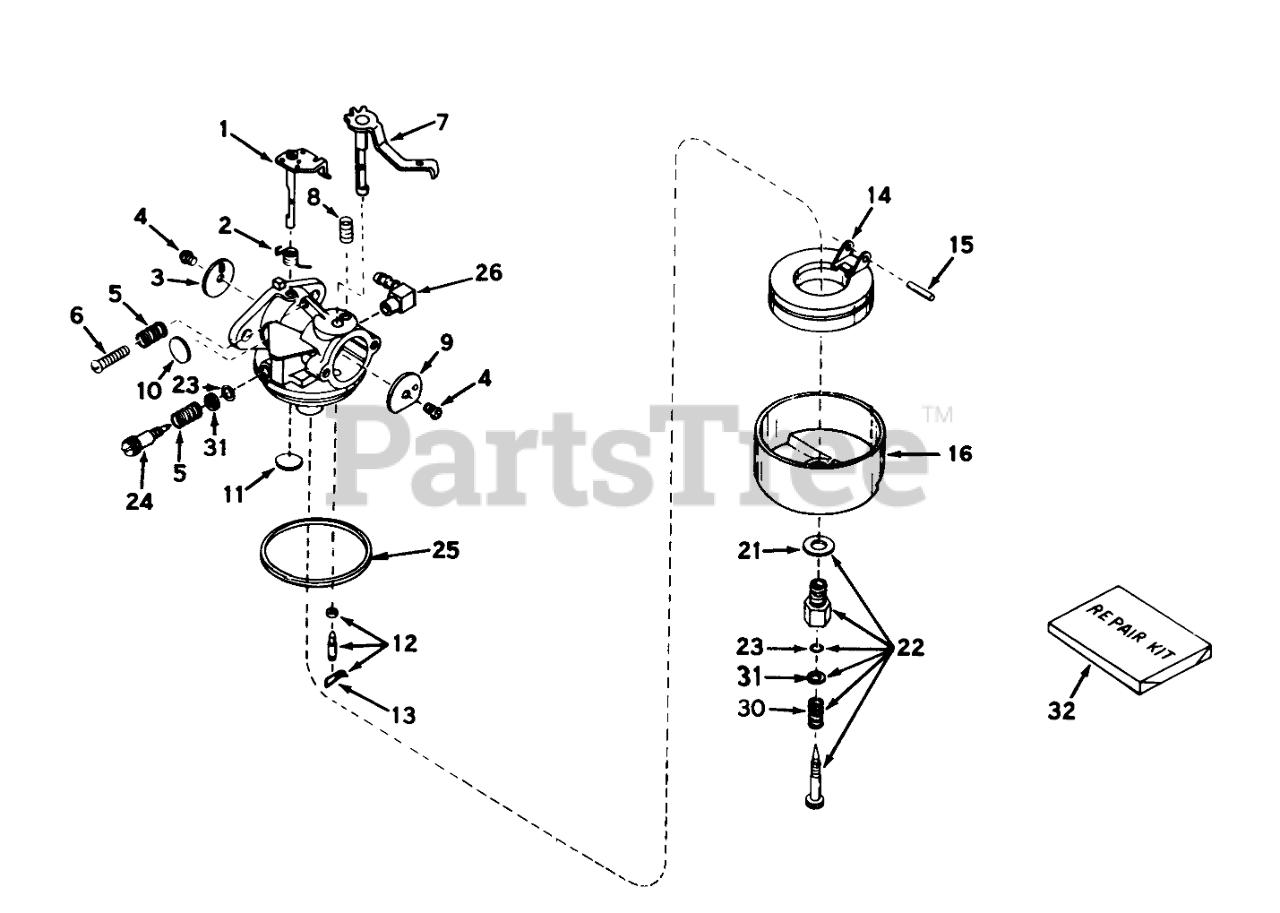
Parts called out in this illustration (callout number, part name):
1	Throttle Shaft and Lever ASM
2	Spring, Throtte Return
3	Shutter-Throttle
4	Screw-Shutter
5	Spring-Tension
6	Screw-Throttle Crack Screw / Idle Speed
7	Shaft/Lever Assy., Choke
8	Spring-Positioning, Choke
9	Shutter-Choke
10	Plug-Welch, Idle Mixture Well
11	Plug-Welch, Atmospheric Vent
12	Inlet Needle, Seat & Clip Assy.(Incl. No.13)
13	Clip-Spring
14	Float,Carburetor
15	Shaft-Float
16	Bowl-Float (no drain)
21	Washer-Bowl Nut
22	Adjustment Screw Assy., Main (Incl. Nos. 21, 23, 30 & 31)
23	"O"Ring
24	Screw, Idle Adj.
25	O Ring-Bowl, Float
26	Fitting-Fuel
32	Kit-Repair
